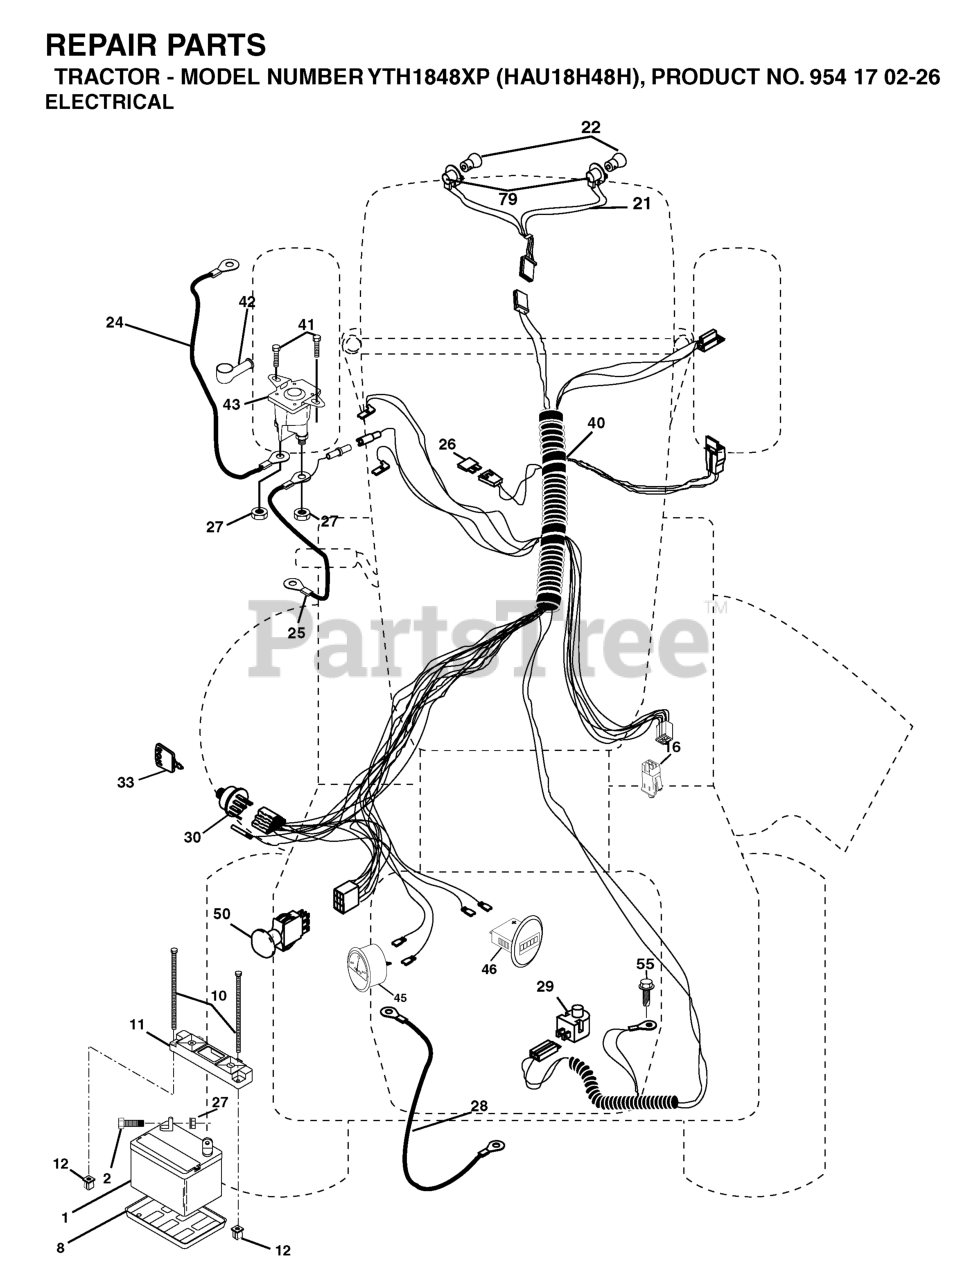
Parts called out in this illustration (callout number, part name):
1	BATTERY 12V .35 AMP
2	BOLT.HEX.1/4.X.3/4.DICHROMATE
8	BATTERY TRAY T
10	BOLT 1/4-20 X 7.5
11	BATTERY HOLDDOWN FRONT MOUNT
12	NUT, PUSH NYLON 1/4" BATTERY
16	SWITCH INTERLOOK PUSH-IN
21	HARNESS.W/LIGHT SOCKET
25	CABLE BATTERY 6 GA 22" W/16W
26	FUSE 20AMP
27	NUT
28	CABLE GROUND 6 GA 21" 90T BLK
29	RP.SWITCH.PLUNGER.NC.GRAY
30	IGNITION SWITCH
33	KEY MLD GEN DELTA
41	SCREW
42	TERMINAL COVER
43	SOLENOID
45	RP AMMETER.ROUND.SILVER.DELTA
46	RP HOURMETER SNAP-IN
50	RP.PTO.SWITCH.8 TERMINAL.BLACK
55	Screw 5/16-18 x 1/2 Hex, Self Tapping 5/16-18 x 1/2
79	BULB HOLDER ASM.
